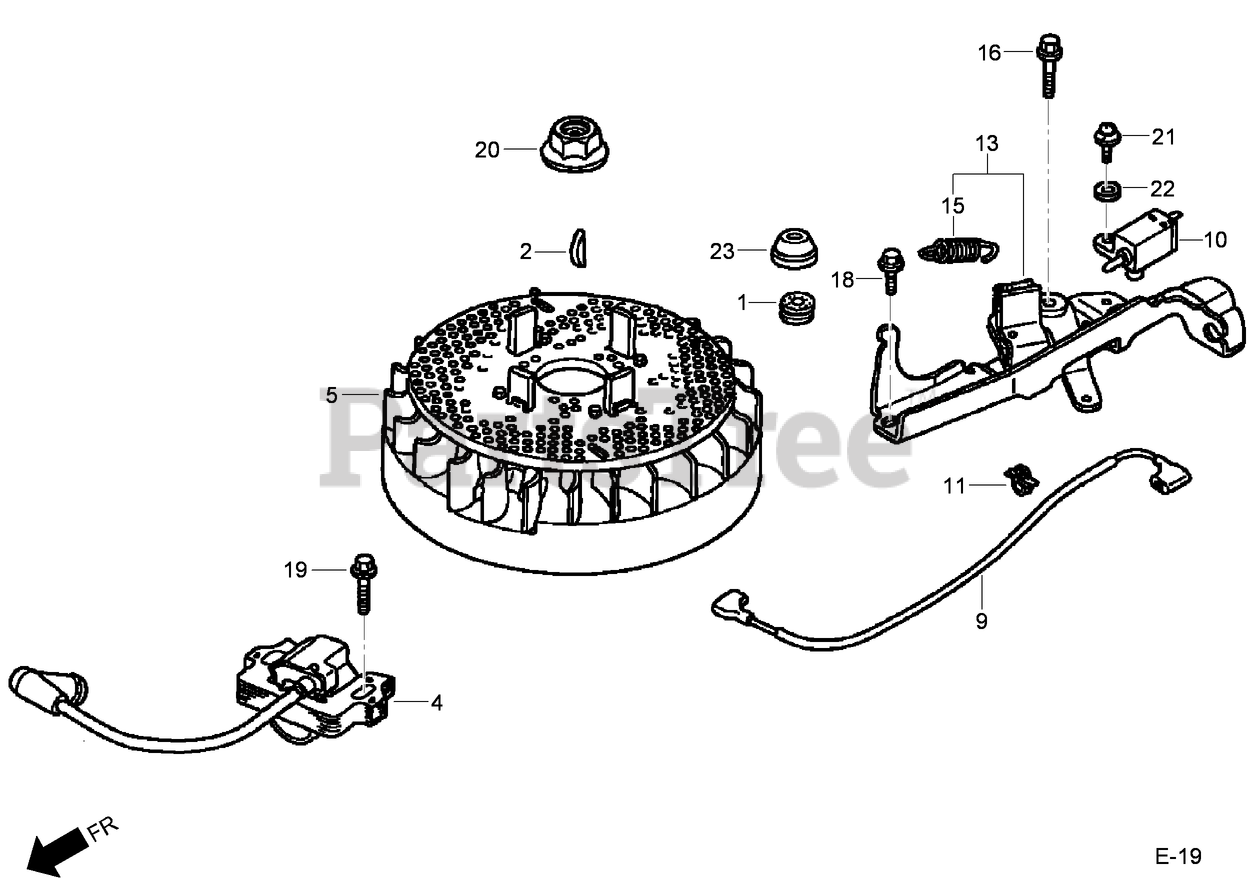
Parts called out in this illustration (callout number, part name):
1	GROMMET A-COVER, REAR (8X16X6.6) (engine serial numbers up to 7132770)
1	GROMMET A-COVER, REAR (8X16X8) (engine serial numbers up to 7132770)
2	KEY-WOODRUFF, SPECIAL (25X18)
4	IGNITION COIL ASM (USE FOR FLYWHEEL OF TEC)
5	FLYWHEEL ASM (USE FOR IGNITION COIL OF TEC)
9	WIRE-SWITCH, STOP
10	ENGINE STOP SWITCH ASM (N C)
11	HOLDER-WIRE (FASTEX)
11	CLIP A-CABLE (3.8MM BLACK) (NIFCO)
13	BRAKE ASM (engine serial numbers up to 7132770)
13	BRAKE ASM (engine serial numbers starting at 7132771)
15	SPRING-LEVER, BRAKE
16	BOLT-FLANGE (6X23) (C T200)
18	BOLT-FLANGE (6X14) (C T200)
19	BOLT-FLANGE (6X23) (C T200)
19	BOLT-FLANGE (6X20) (C T200) (engine serial numbers up to 6702082)
20	NUT-SPECIAL (14 mm)
21	SCREW-WASHER (4X12)
22	WASHER-PLAIN (4MM)
23	GROMMET-PLATE, BRAKE (engine serial numbers starting at 7132771)
